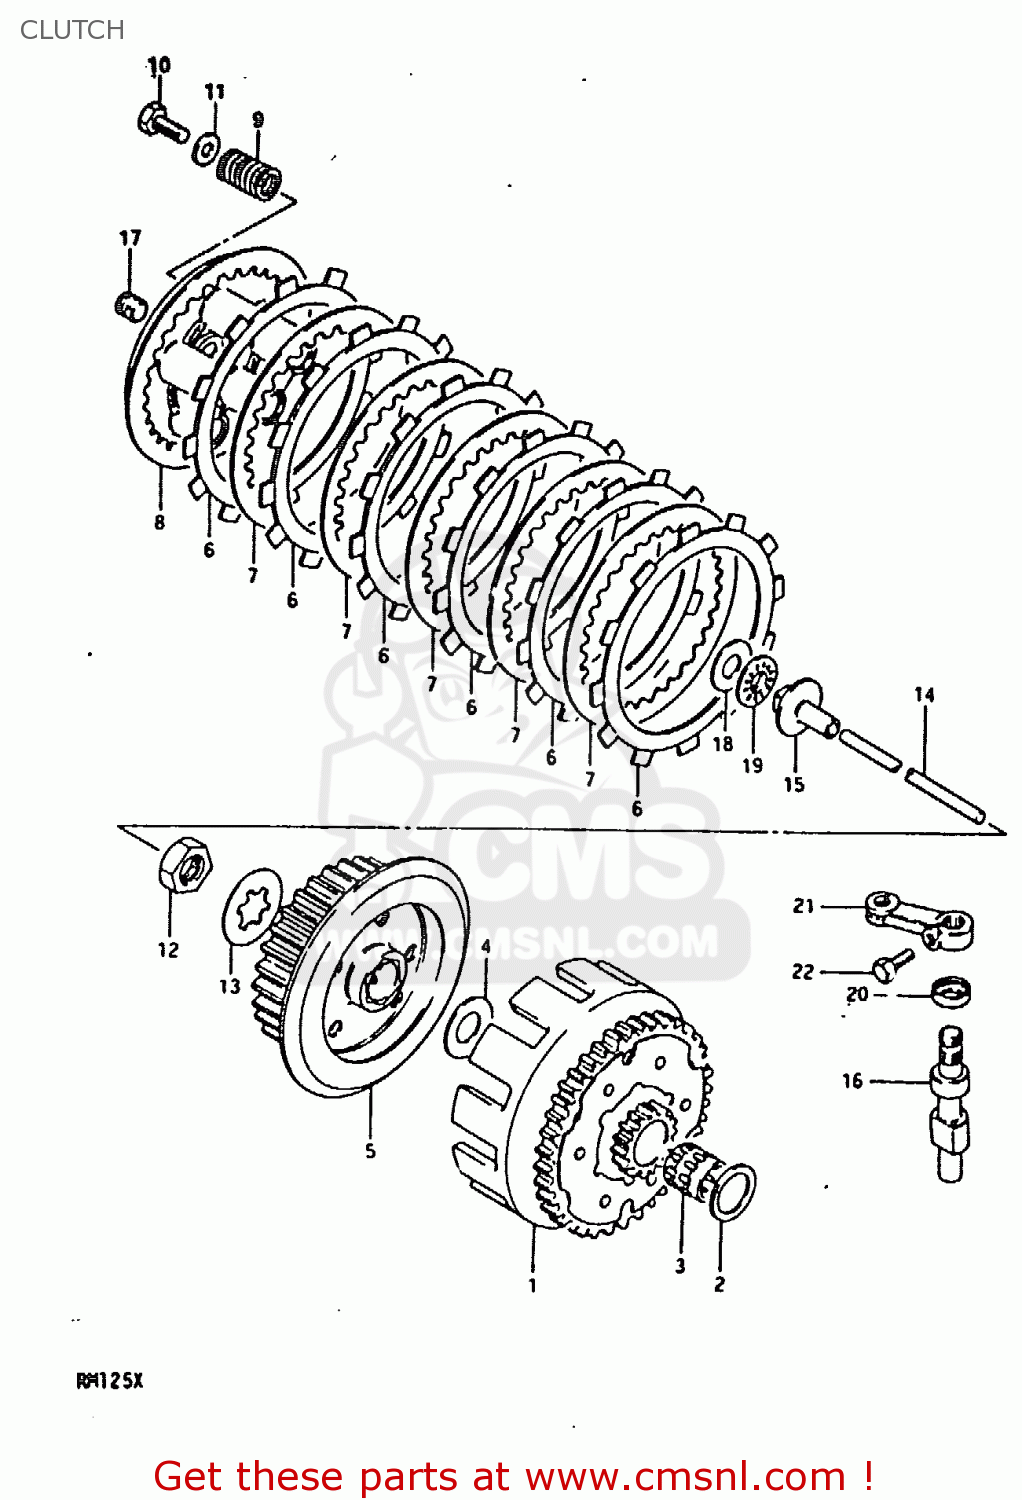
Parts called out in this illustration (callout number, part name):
1	GEAR ASSEMBLY,PRIMARY DRIVE
2	WASHER
3	BEARING(20X25X26)
4	WASHER
5	HUB,CLUTCH SLEEVE
6	PLATE,CLUTCH DRIVE
7	PLATE,CLUTCH DRIVEN
8	DISC,CLUTCH PRESSURE
9	SPRING
10	BOLT(5X16)
11	WASHER (5.5X16X1.2)
12	NUT
13	WASHER,LOCK
14	ROD,CLUTCH PUSH
15	PIECE,CLUTCH PUSH
16	CAMSHAFT,CLUTCH RELEASE
17	SCREW
18	WASHER
19	BEARING(15X28X2)
20	OIL SEAL
21	ARM,CLUTCH RELEASE
22	BOLT, UPPER
